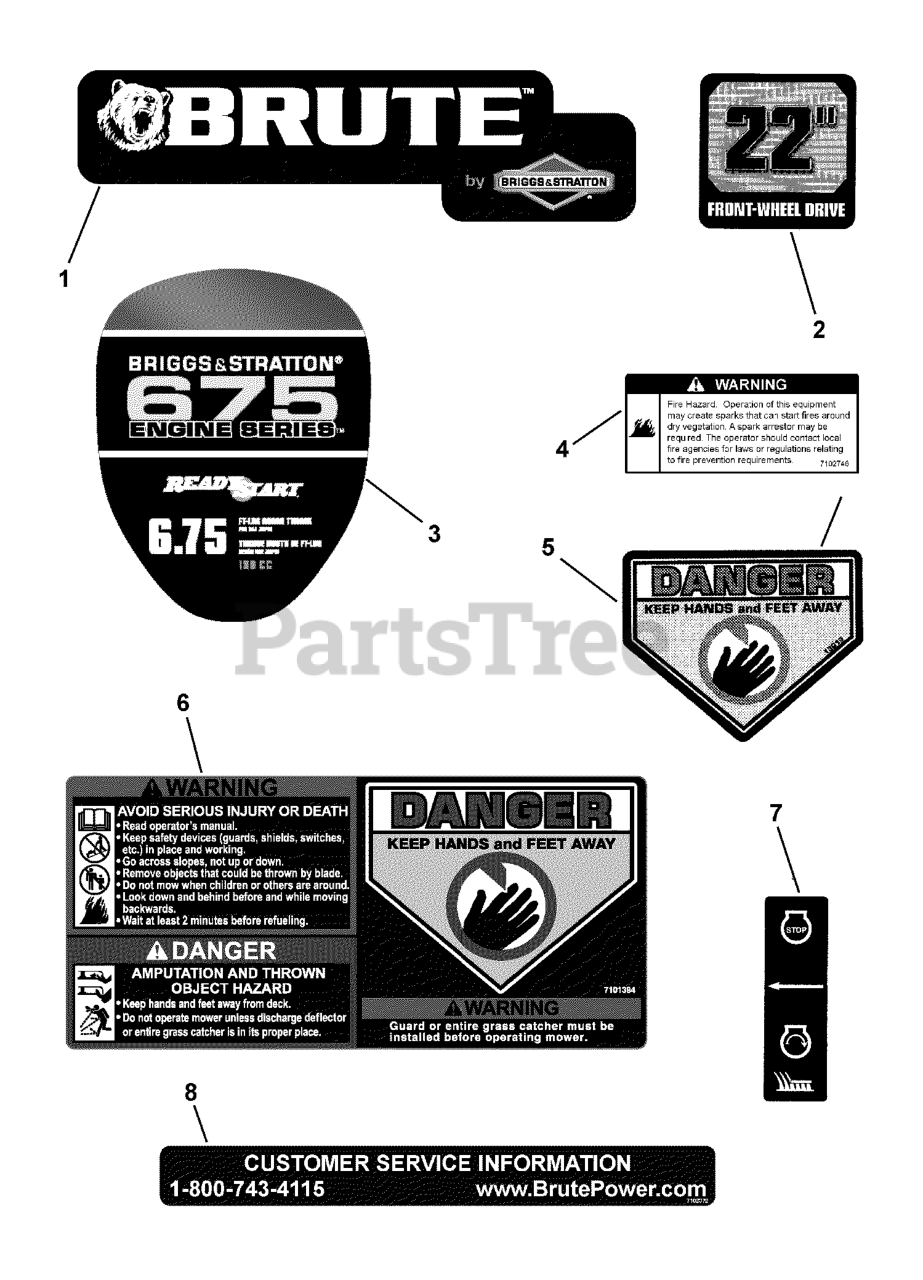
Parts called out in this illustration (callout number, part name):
1	DECAL, Brute Walk-Behind Mower
2	DECAL, 22" Front Wheel Drive Brute
3	DECAL, Engine 675, Brute
4	DECAL, Spark Arrestor
5	DECAL, Danger, Cut Finger
6	DECAL, Warning, Rear Discharge Door
7	DECAL, OPC Bail International Symbol
8	DECAL, Customer Service, Brute
